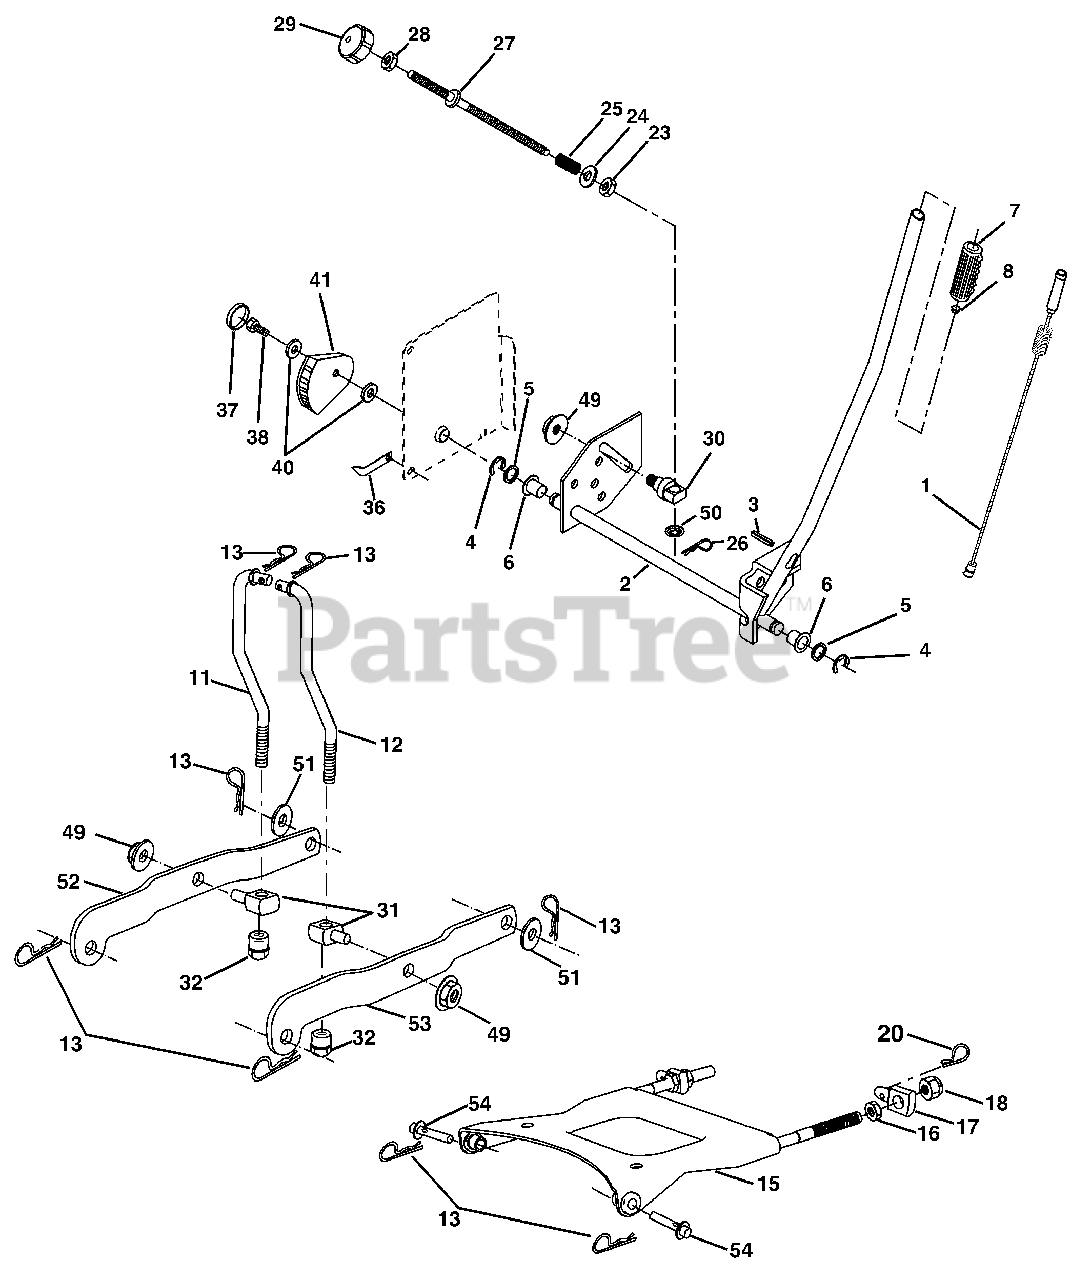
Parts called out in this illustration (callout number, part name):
1	Wire Asm Inner/Sprg W/plunger
2	Shaft Asm Lift RH w/Inf
3	Pin Groove
4	E Ring #5133-62
5	Washer 21/32 x 1 x 21 Ga.
6	Bearing Nylon Blk 629 Id
7	Grip Handle
8	Button Plunger
11	Link Lift LH
12	Link Lift RH
13	Retainer Spring
15	Plate Asm. Suspension Front
16	Nut Jam Hex 1/2-13 unc
17	Trunnion Front Susp.
18	Nut Lock w/Wsh 1/2-13 unc
20	Retainer Spring
23	Nut Special
24	Washer 13/32 x 5/8 x 16 Ga.
25	Spring
26	Retainer Clip
27	Rod Adj Lift
28	Nut Hex Jam 3/8-16 unc
29	Knob Inf 3/8-16 unc Blk W/sym
30	Trunnion Infin Height
31	Trunnion Susp. Arm
32	Nut Lift Link 7/16-20
36	Pointer Height Indicator
37	Plug Hole Blk 1.485/1.515 Dia.
38	Screw 5/16-18 x 1
40	Washer 11/32 x 1-1/2 10 Ga.
41	Indicator Height STLT
49	Nut Hex Flange Lock
50	Nut PUsh Phos & Oil
51	Washer 17/32 x 7/8 x 16 Ga.
52	Arm Susp. Rear LH
53	Arm Susp. Rear RH
54	Pin
